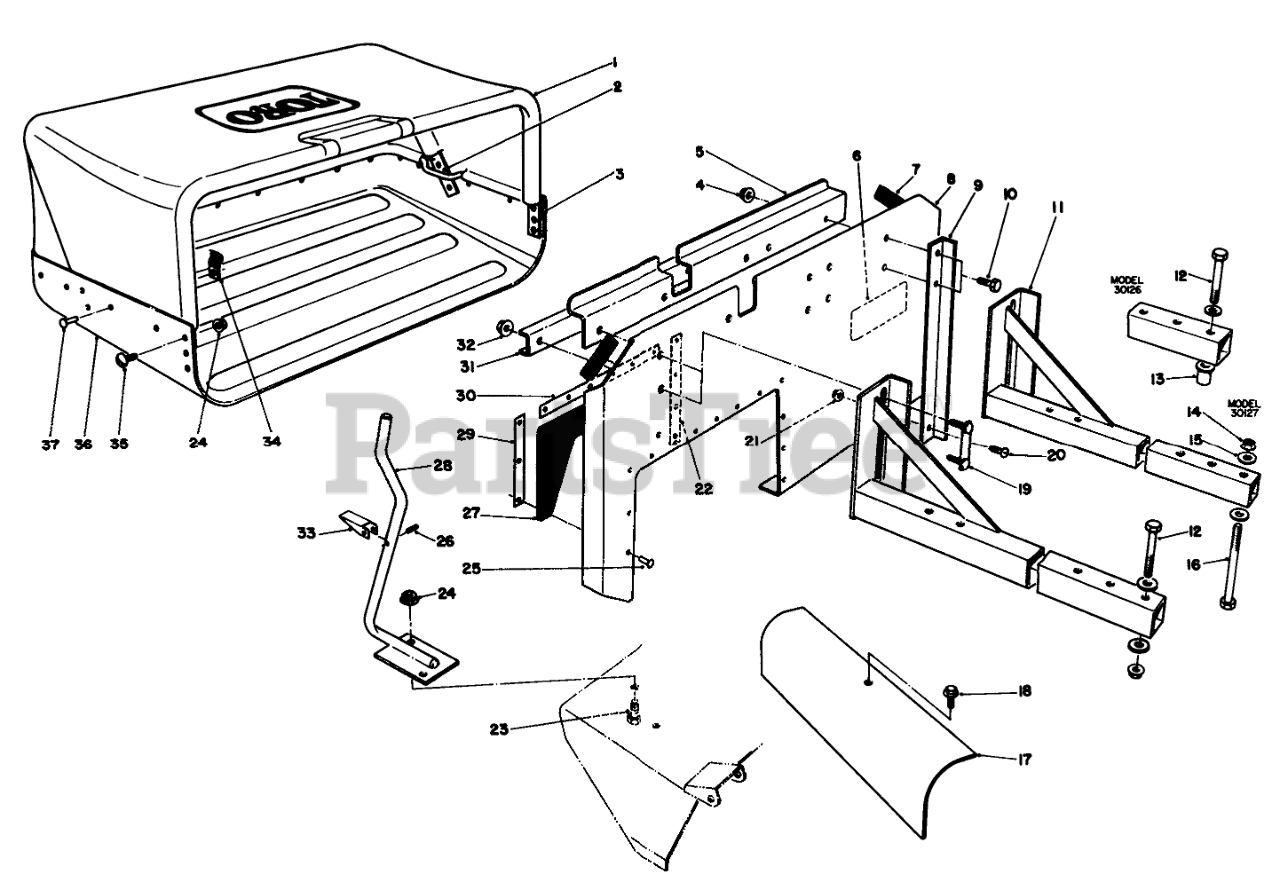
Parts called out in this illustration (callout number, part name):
1	Bag-Cloth
2	Rod-Cloth
3	Tube-Bag Support
4	NUT-HHF, WHIZ
5	Support-Bag
6	DECAL-DANGER
7	PAD-RUBBER
8	Panel-Back
9	Support-Panel
10	SCREW-HH
11	Beam-Mounting
12	SCREW-HH
13	RIVSERT
14	NUT-LOCK, NI
15	WASHER-FLAT
16	SCREW-HH
17	Baffle-44in
18	Screw-HH
19	Retainer-Bolt
21	NUT-LOCK, HHF
22	STRIP-Seal, 10in
23	SCREW-HH
24	NUT-HF
25	RIVET-POP
26	PIN-SPRING
27	Seal-Panel Model 30126
28	Rod-Lockup
29	STRIP
30	STRIP-SEAL, 16in
31	Support-Channel
32	NUT-LOCK, FLANGE
33	LATCH-LOCKUP
34	CLIP-HALF
35	SCREW-PPH
36	TRAY-BAG, GRASS
37	RIVET-BLIND
